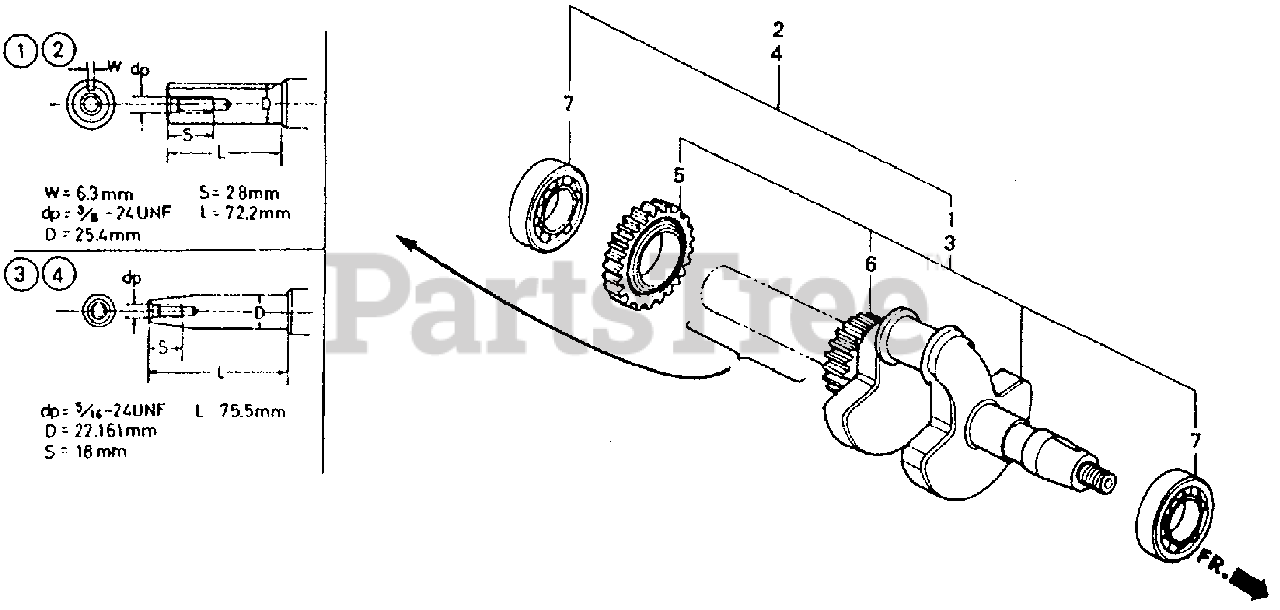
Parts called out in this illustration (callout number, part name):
3	CRANKSHAFT (V-TYPE)
4	CRANKSHAFT (V-TYPE)
5	GEAR, BALANCER
6	GEAR, TIMING
7	BEARING, RADIAL BALL (6206)
